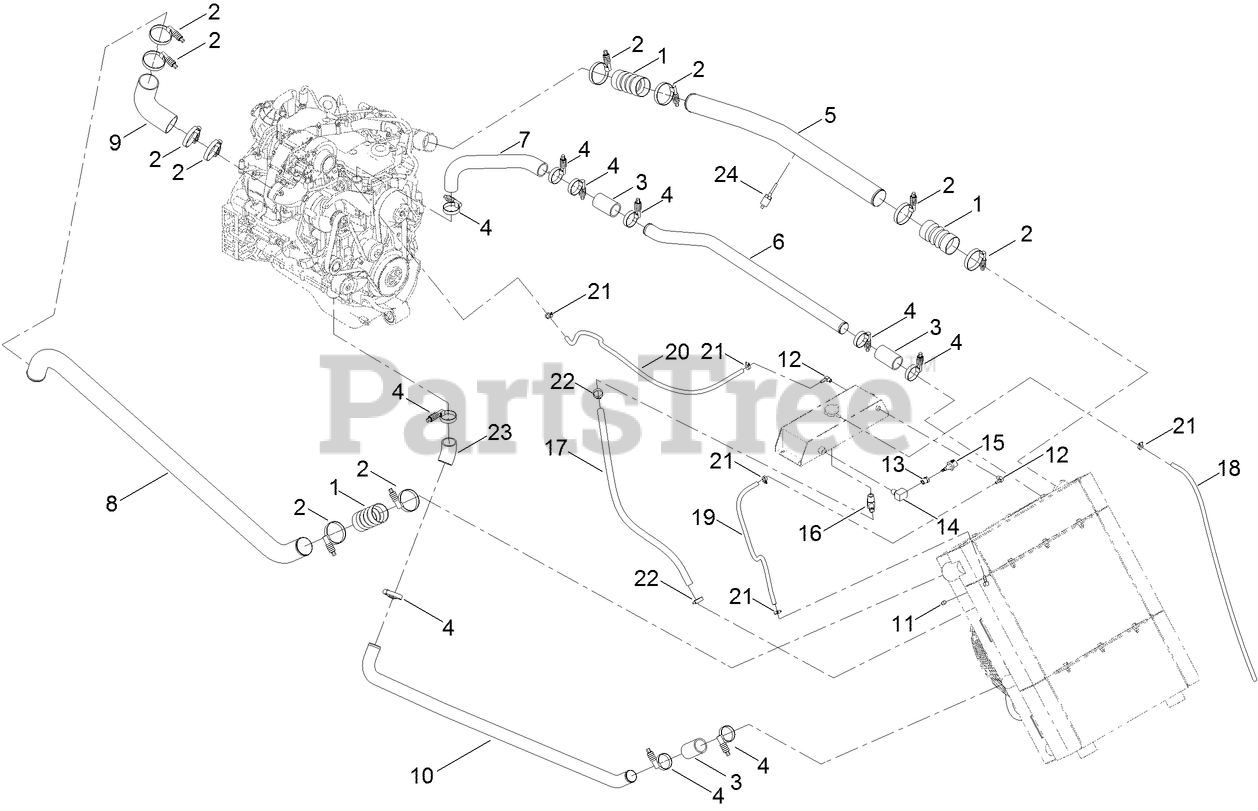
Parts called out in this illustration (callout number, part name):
1	CONNECTOR-HOSE
2	CLAMP-TORQUE, CONSTANT
3	HOSE-CONNECTING
4	CLAMP-TORQUE, CONSTANT
5	TUBE-CHARGE AIR OUT
6	TUBE-RADIATOR
7	HOSE-RADIATOR, MOLDED
8	TUBE-CHARGE AIR IN
9	ELBOW-90
10	TUBE-RADIATOR, OUT
11	PLUG-PIPE, SQH
12	FITTING-ELBOW, 90
13	BUSHING
14	ELBOW-STREET, 90 DEG
15	SENSOR-LEVEL, COOLANT
16	STEM-90, BEAD HOSE
17	HOSE-COOLANT
18	HOSE-COOLANT
19	HOSE-COOLANT
20	HOSE-COOLANT
21	CLAMP-HOSE
22	CLAMP-HOSE
23	HOSE-COOLANT, 45 DEGREE
24	TRANSDUCER-TEMPERATURE
